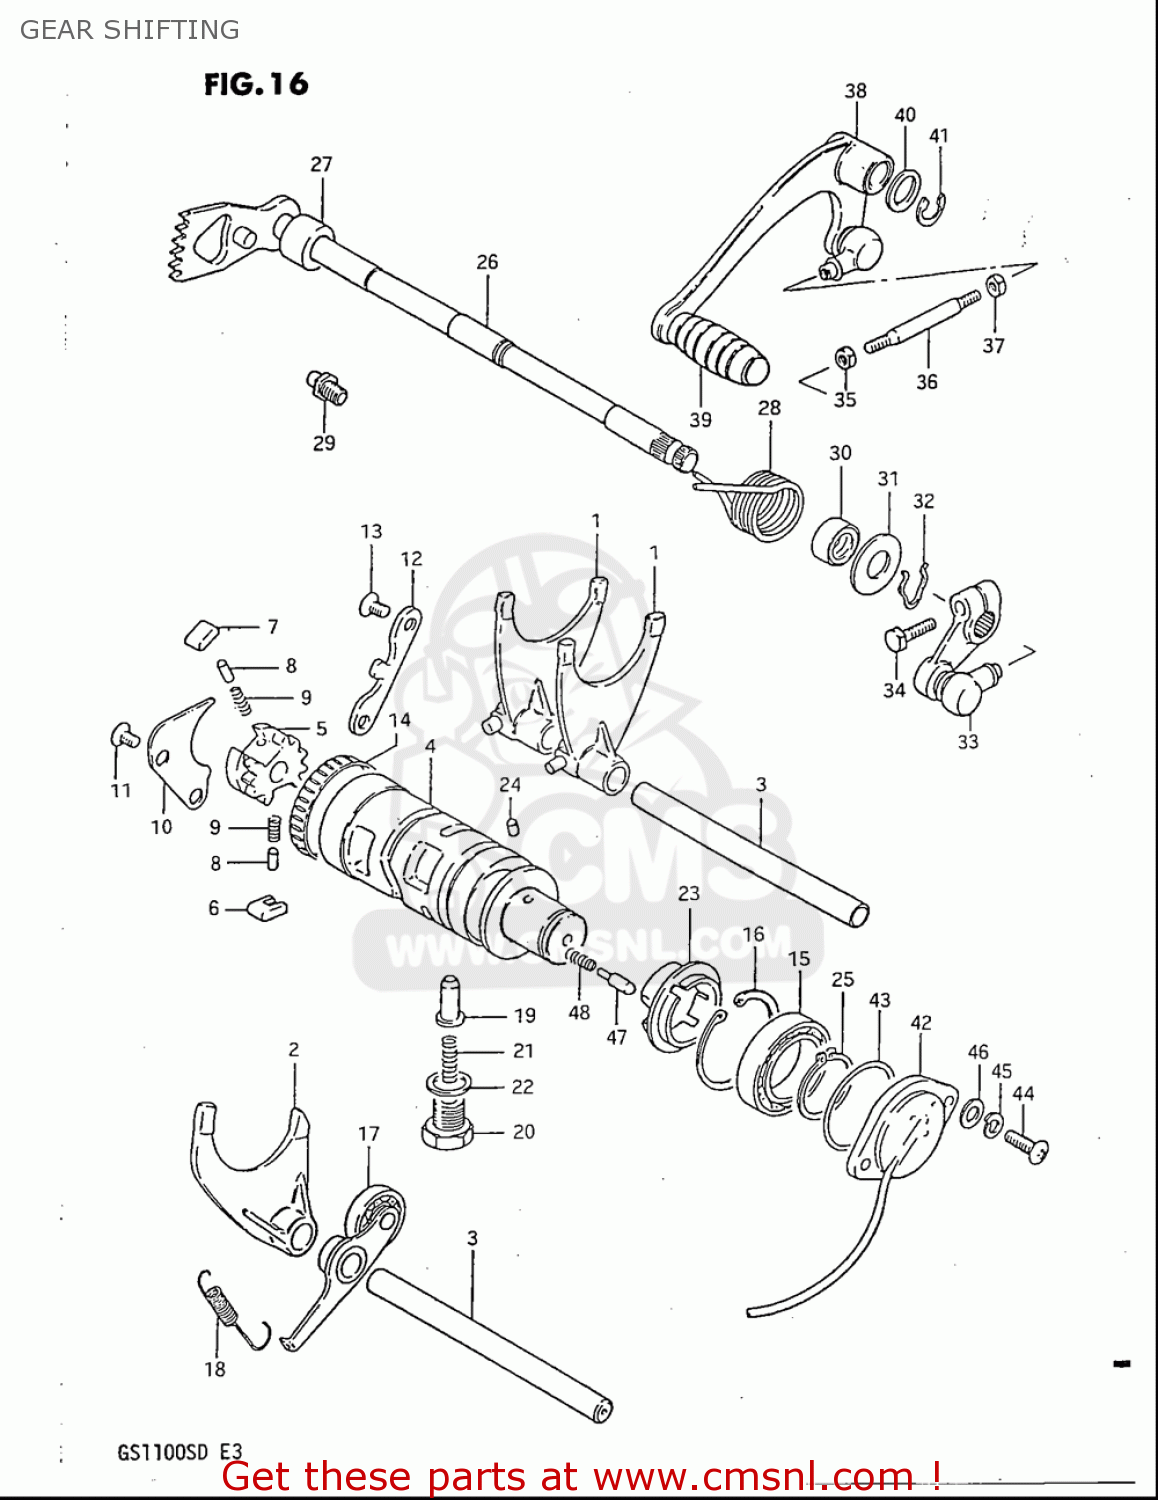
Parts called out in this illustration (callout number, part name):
1	FORK,GEAR SHIFT NO.1
2	FORK,GEAR SHIFT NO.2
3	SHAFT,GEAR SHIFT FORK
4	CAM,GEAR SHIFT
5	GEAR,GEAR SHIFT CAM DRIVEN
6	PAWL,GEAR SHIFT NO.1
7	PAWL,GEAR SHIFT NO.2
8	PIN(5X8)
9	SPRING
10	LIFTER,GEAR SHIFT POLE
11	SCREW
12	GUIDE,GEAR SHIFT CAM
13	SCREW
14	BEARING(43X49X12)
15	BEARING
16	CIRCLIP
17	STOPPER,GEAR SHIFT CAM
18	SPRING
19	STOPPER,GEAR SHIFT CAM NO.2
20	HOLDER,GEAR SHIFT CAM STOP SPR
21	SPRING
22	GASKET(14X19.2X2) (NAS)
23	PLATE,GEAR SHIFT CAM STOPPER
24	PIN
25	CIRCLIP
26	SHAFT,GEAR SHIFT
27	SPACER(12X20X15.3)
28	SPRING
29	STOPPER,GEAR SHIFT ARM
30	SEAL,OIL (12X22X9)
31	WASHER (12.5X26X1.6)
32	CIRCLIP,12 MM
33	ARM,GEAR SHIFT LINK
34	BOLT
35	NUT
36	ROD,GEAR SHIFT LINK
37	NUT
38	LEVER ASSY,GEAR SHIFT
39	RUBBER,PEDAL
40	WASHER(12.5X20X1)
41	CIRCLIP,12 MM
42	TERMINAL BASE,NEUTRAL SWITCH
43	O RING(D:2.4,ID:36.5)
44	SCREW
45	WASHER,LOCK
46	WASHER
47	PIN(5X15.5)
48	SPRING
